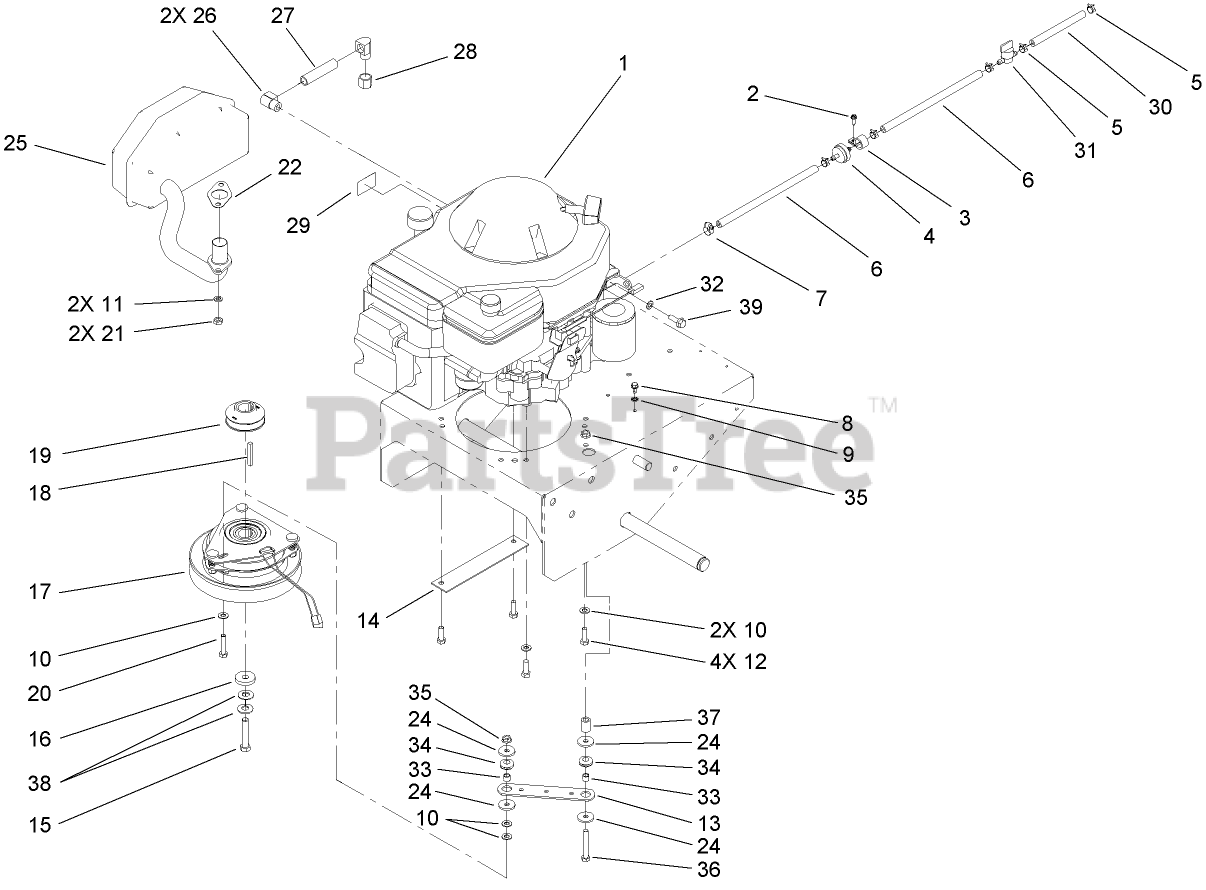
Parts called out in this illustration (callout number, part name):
2	SCREW-SHWH
3	CLAMP-CABLE
4	FILTER-FUEL
5	CLAMP-HOSE
6	HOSE-FUEL
7	CLAMP-WORM
8	SCREW
9	WASHER-LOCK/EXT
10	WASHER-PLAIN
11	WASHER-LOCK
12	SCREW-HH
13	STRAP-CLUTCH, BRAKE
14	GUARD-PULLEY
15	SCREW-HH
16	WASHER
17	CLUTCH / BRAKE ASM
18	KEY-SQUARE
19	PULLEY-DRIVE
20	SCREW-HH
21	NUT-MUFFLER
22	GASKET-EXHAUST
24	WASHER
25	MUFFLER
26	ELBOW-STREET, 90 DEG
27	NIPPLE-PIPE
28	CAP-PIPE
29	DECAL-WARNING
30	HOSE-FUEL
31	VALVE-FUEL
32	WASHER-LOCK
33	SPACER
34	GROMMET
35	NUT-HF
36	SCREW-HH
37	TUBE-RETAINER
38	WASHER-SPRING
39	SCREW-HHF
